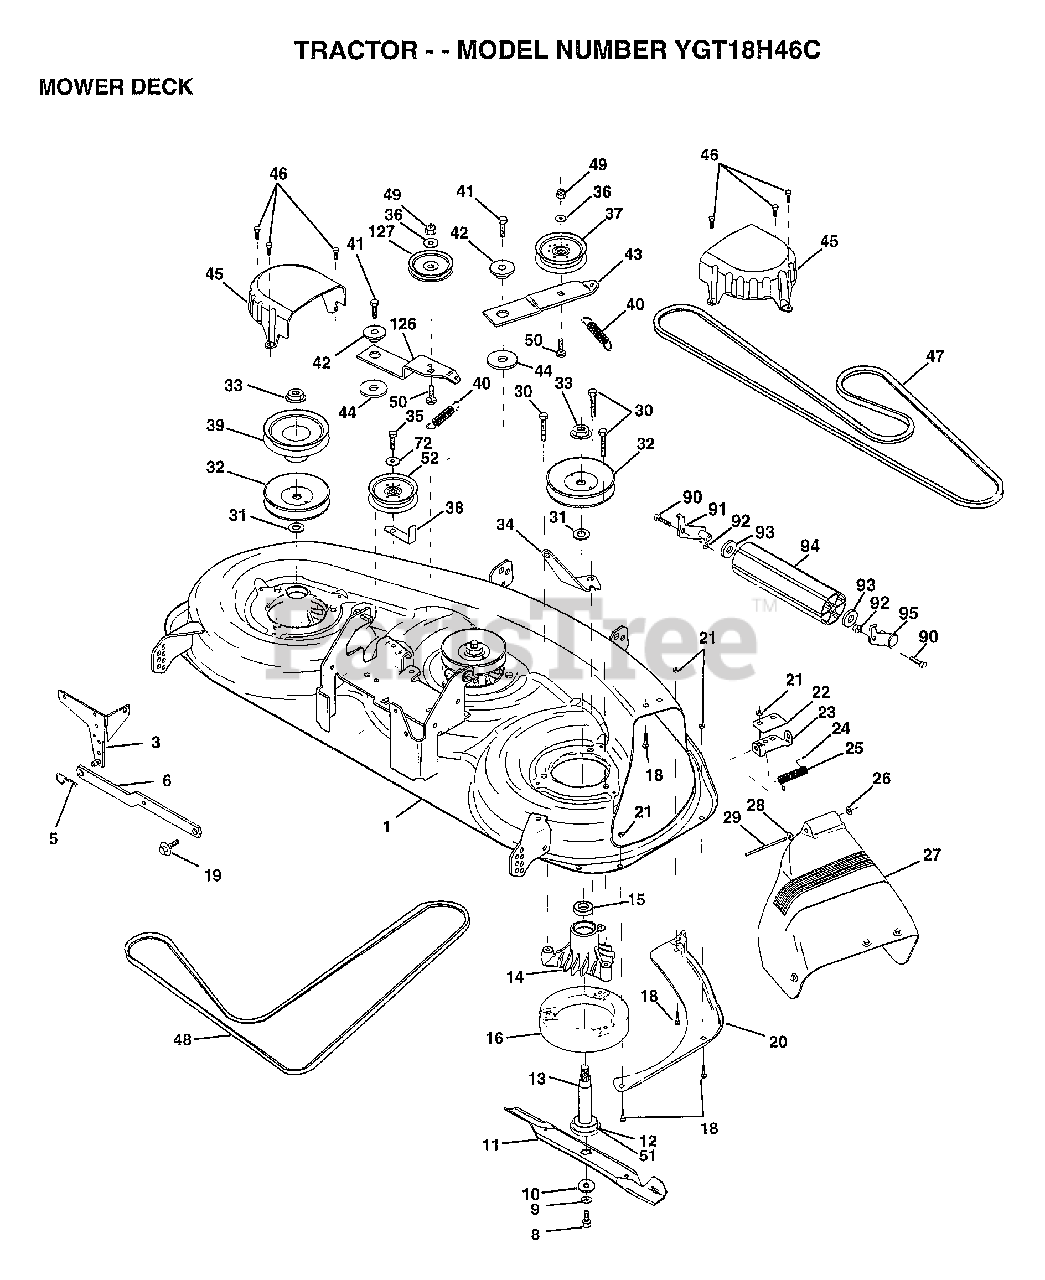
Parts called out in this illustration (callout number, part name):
1	"MOWER ASM 46"""
3	BRKT.ASM.SW.44/50
8	BLADE BOLT
10	WASHER.HARD.BLADE
11	"BLADE.HIGHLIFT46"""
12	BEARING.BALL
13	SHAFT.ASM.W/BRNG
14	HOUSING.MAND.44.V
15	BEARING
16	STRIPPER RND MWR
18	BOLT
19	BOLT SHD 5/16-18
20	BAFFFLE.VORTEX.46
22	STIFFENER BRKT
23	DEFLECTOR BRKT
24	CAP-SLEEVE LT
26	NUT PUSH M
27	SHIELD DEFLECTOR
28	WASHER
29	HINGE ROD
30	"SCREW-THD ROLL,WA"
31	WASHER
32	PULLEY.MAND.36/46
34	ANCHOR.SPRING.46
35	SCREW LT
36	WASHER
37	FLAT IDLER PULLEY
38	"KEEPER BELT,IDLER"
39	PULLEY.DRV.DCK.46
40	"SPRING.SEC.44""VEN"
41	SCREW
42	SPACER RETAINER
43	ARM.IDLER.DECK.46
44	HARDENED WASHER
45	COVER.MANDREL.46
46	SCREW.1/4-20X5/8
47	BELT-V.SEC.46.KEL
48	BELT V PRIM 50
50	BOLT.3/8-16X1.50
51	WASHER.FELT.
52	"PULLEY IDLER,FLAT"
72	WASHER HYT
90	BOLT
92	NUT
93	WASHER
116	BOLT.SHOULDER
117	WHEEL GAGE DONUT
118	LOCKNUT
119	WASHER
126	ARM.IDLER.PRIM.46
127	PULLEY.IDLER.4.25
